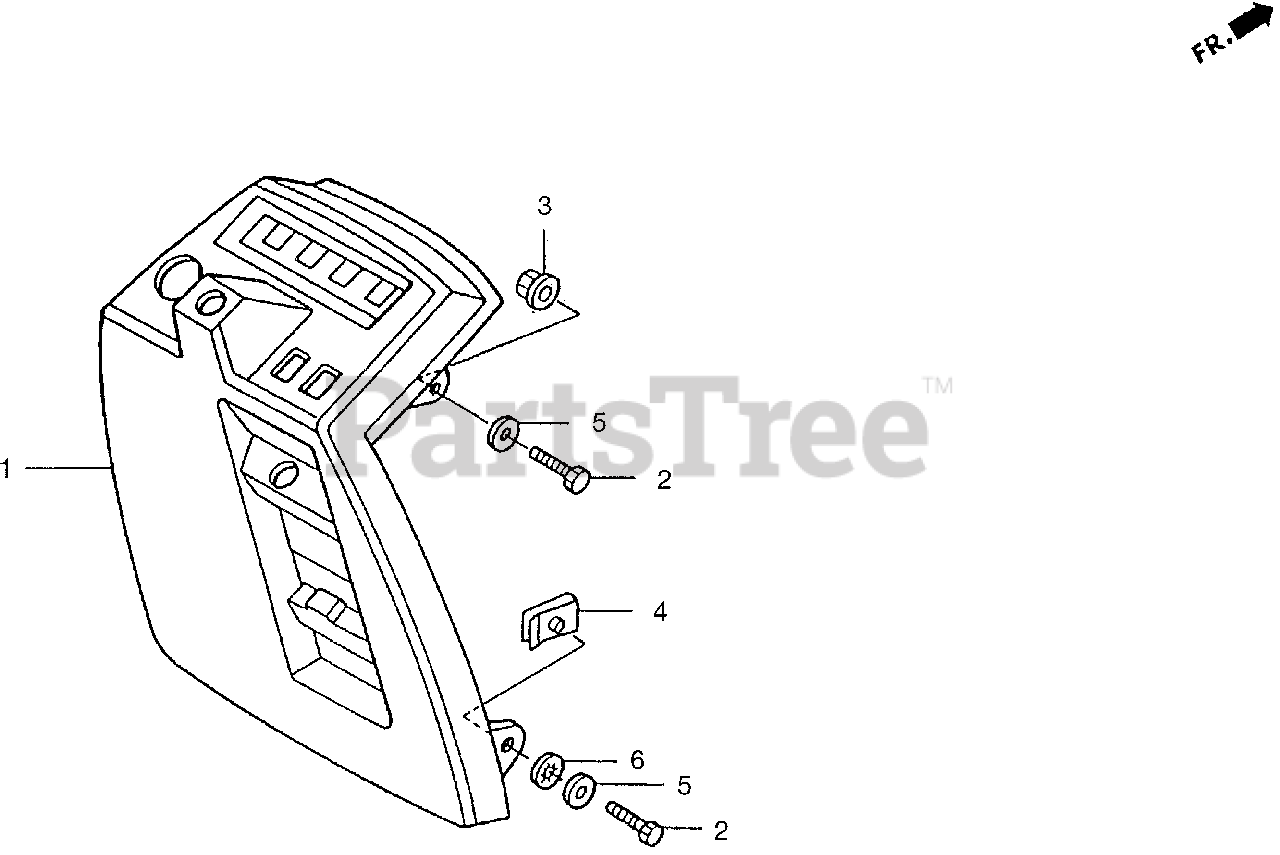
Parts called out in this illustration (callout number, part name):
1	PANEL, INSTRUMENT
2	BOLT, HEX. (8X20)
3	NUT, FLANGE (8MM)
4	NUT, SPECIAL (8MM)
5	WASHER, CONSOLE
6	WASHER, TRANSMISSION MOUNTING
6	WASHER, STAR
